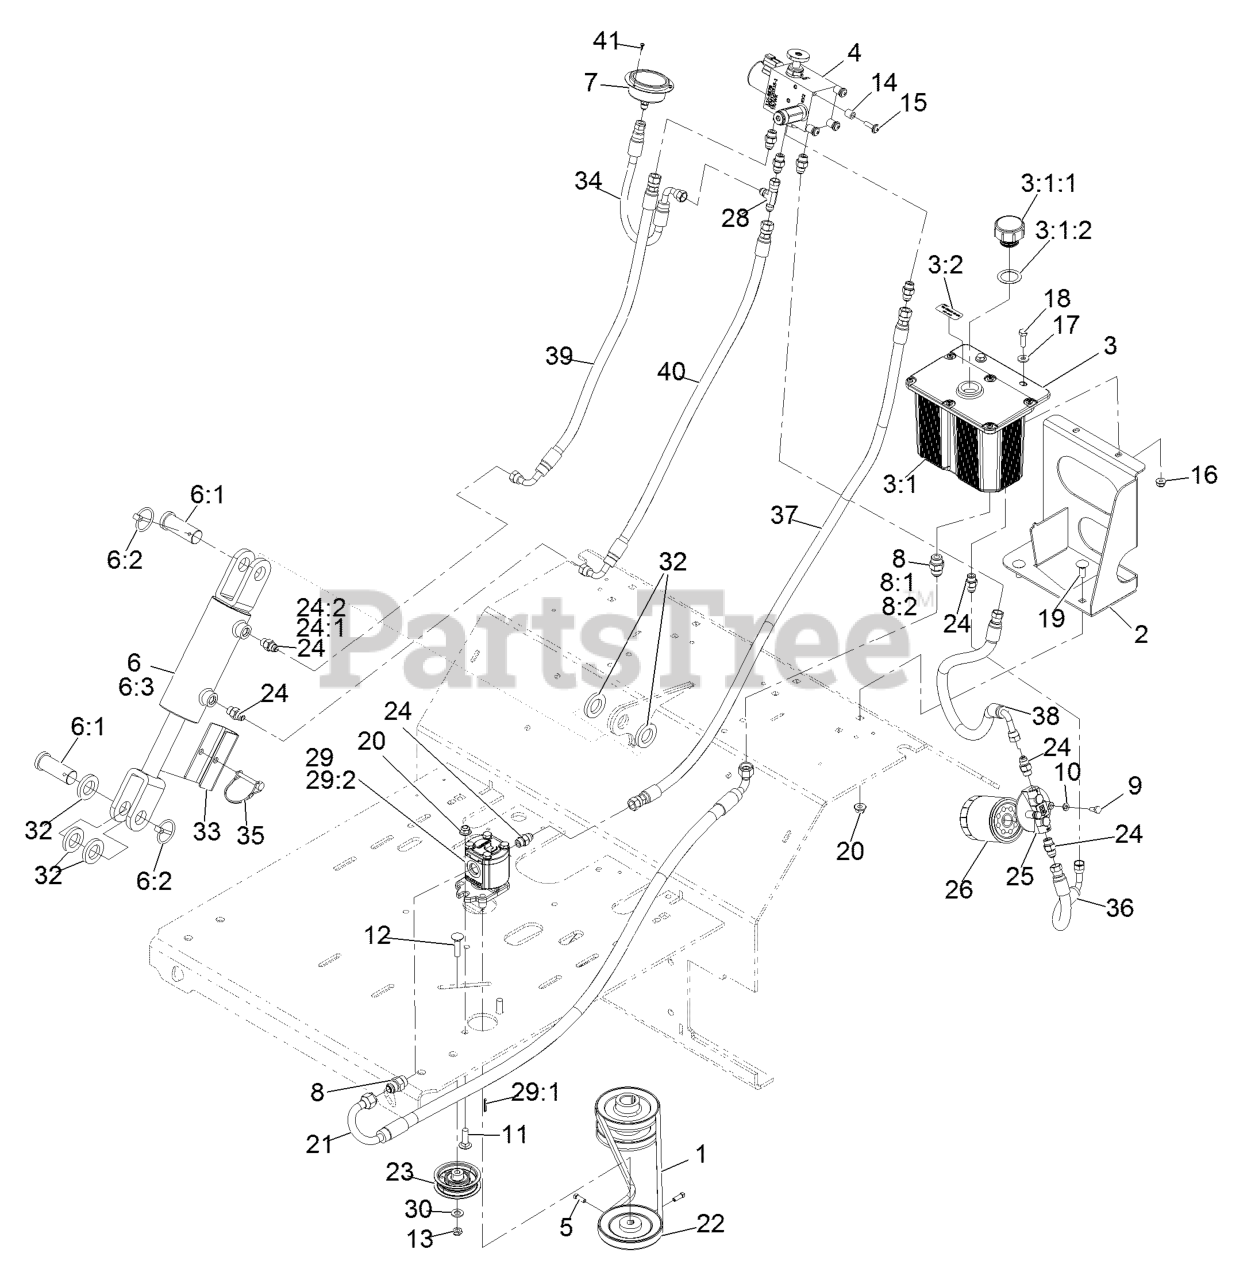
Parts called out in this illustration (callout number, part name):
1	BELT-4L SECTION
2	BRACKET-TANK, HYDRAULIC
3	ASM-RESERVOIR W/DECAL
3:1	Tank-Hydraulic
3:1:1	Cap-Reservoir, HYD
3:1:2	GASKET-CAP
3:2	DECAL-HYDRO OIL AW-32
4	VALVE-MANIFOLD
5	SCREW-SQH
6	HYD CYLINDER ASM
6:1	PIN-CLEVIS
6:2	PIN-LYNCH
6:3	SEAL KIT
7	GAUGE-PRESSURE
8	FITTING-STRAIGHT
9	SCREW-HH
10	WASHER-LOCK
11	BOLT-CARR
12	SCREW-CARR
15	SCREW-PPH
16	NUT-HF, NI
17	WASHER-FLAT
18	SCREW-HH
19	BOLT-CARR
20	NUT-HF, NI
21	HOSE-HYDRAULIC
23	PULLEY-IDLER, FLAT
24	FITTING-STRAIGHT
25	HEAD-FILTER
26	FILTER-25 MICRON, BI-DIRE
28	FITTING-HYD, TEE
29	HYDRAULIC PUMP ASM
29:1	KEY-SQUARE
29:2	SEAL KIT
30	WASHER-FLAT
33	STOP-CYLINDER
34	HOSE-HYDRAULIC, HP
36	HOSE-HYDRAULIC, LP
37	HOSE-HYDRAULIC
38	HOSE-HYDRAULIC
39	HOSE-HYDRAULIC
40	HOSE-HYDRAULIC, HP
41	SCREW-TAP
